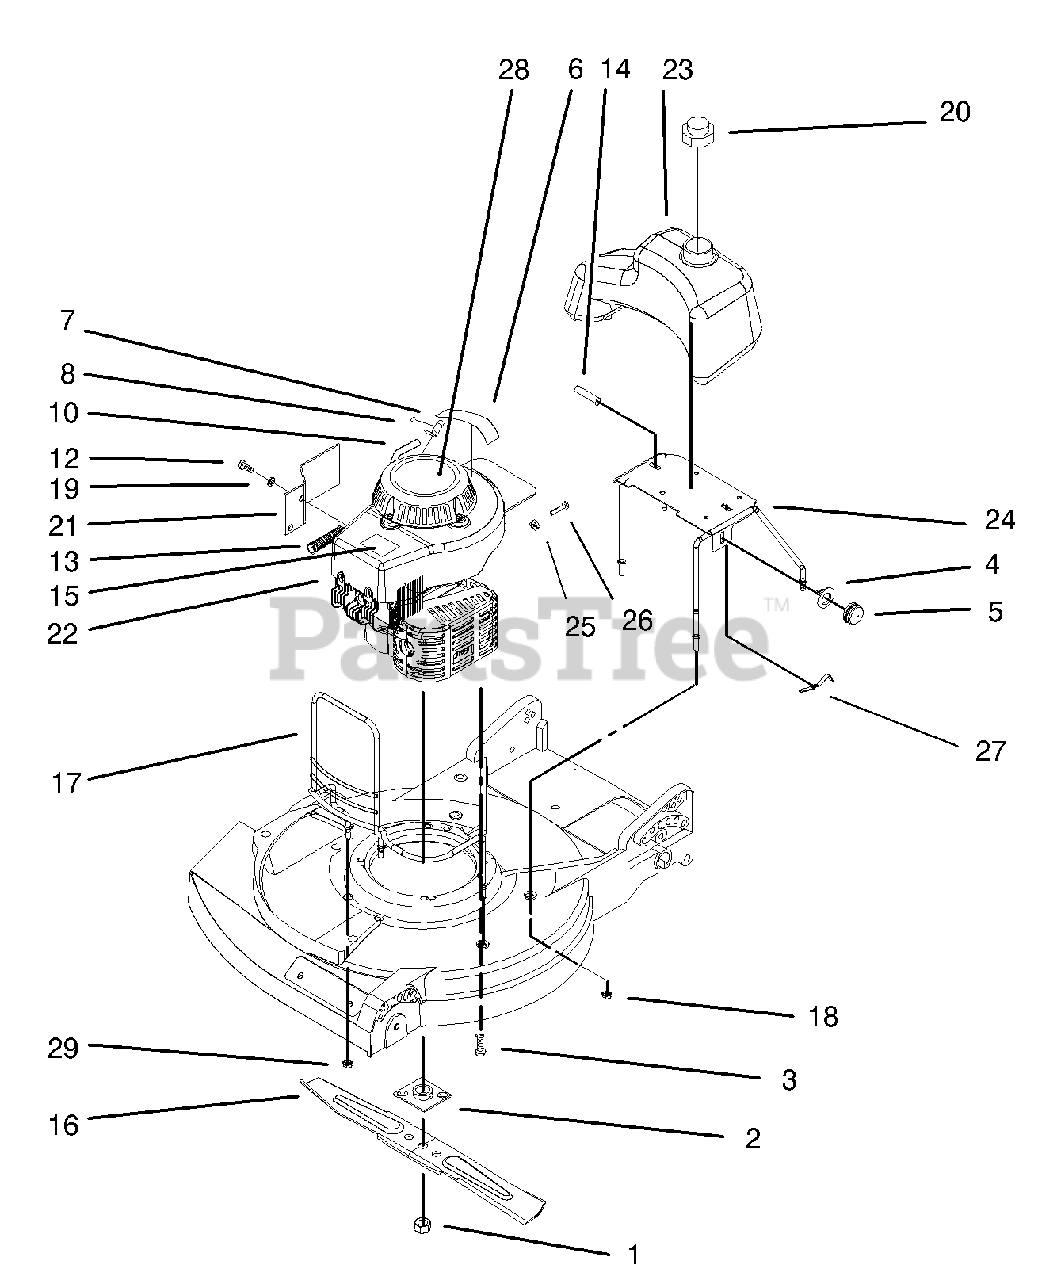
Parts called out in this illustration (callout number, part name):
1	NUT-BLADE
2	PLATE & COLLAR ASM
3	SCREW-HH, SEMS
4	BODY-PRIMER
5	BULB-PRIMER
6	DECAL-FUEL MIX
7	STOP-ROPE
10	LINE-FUEL
12	SCREW-HH
13	SPRING-COMPRESSION
14	PLUG-CAP
15	DECAL-LAWN BOY
16	Blade
17	GUARD-MUFFLER
18	NUT-LOCK, NI
19	WASHER-LOCK
20	FUEL & OIL CAP ASM
21	GUARD-BRAKE S
22	ENGINE ASM
23	TANK - FUEL
24	TANK BRACKET ASM
25	NUT-HEX
28	DECAL - RECOIL
29	NUT-LOCK, NI
